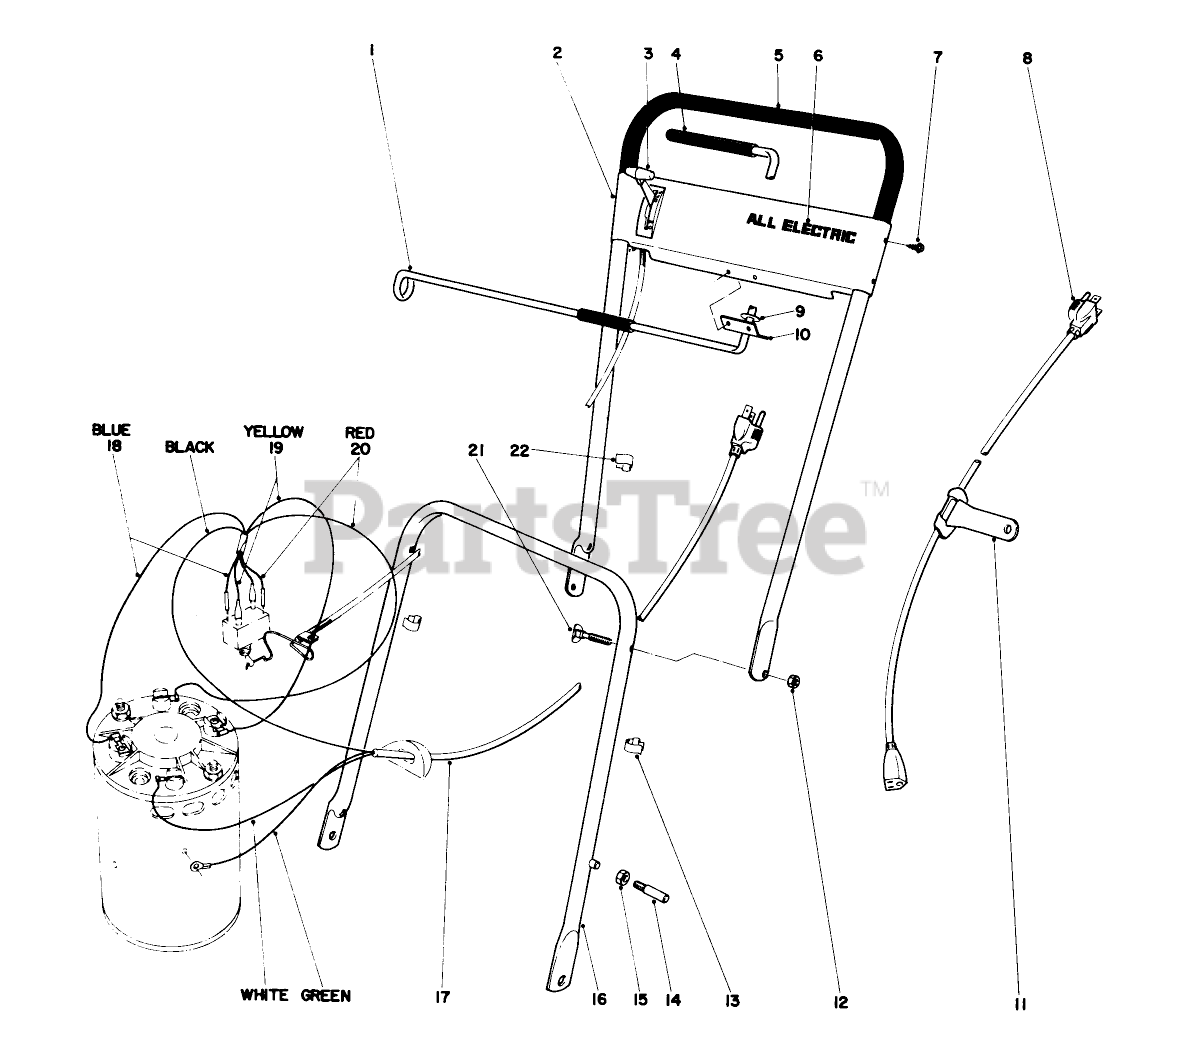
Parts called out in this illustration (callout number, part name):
1	Pivot Rod & Bracket Assembly (Incl. Ref. 9-10)
2	Escutcheon Plate
3	Switch Control
4	Grip-Pivot Rod
5	Upper Handle w/Grip
6	Decal
7	SCREW-HWHTF
8	Cord Assembly (Incl. Ref. 11)
9	WASHER-PLAIN
10	Bracket-Escutcheon
11	Cord Strain Relief
12	Nut
13	Cord Clip
14	Handle Pin
15	Nut
16	LWR HANDLE STAKED ASM
17	Cord Assembly
18	Lead Wire (Blue)
19	Lead Wire (Yellow)
20	Lead Wire (Red)
21	1-1/4 LG HANDLE SCREW
22	CONTROL WIRE CLIP
